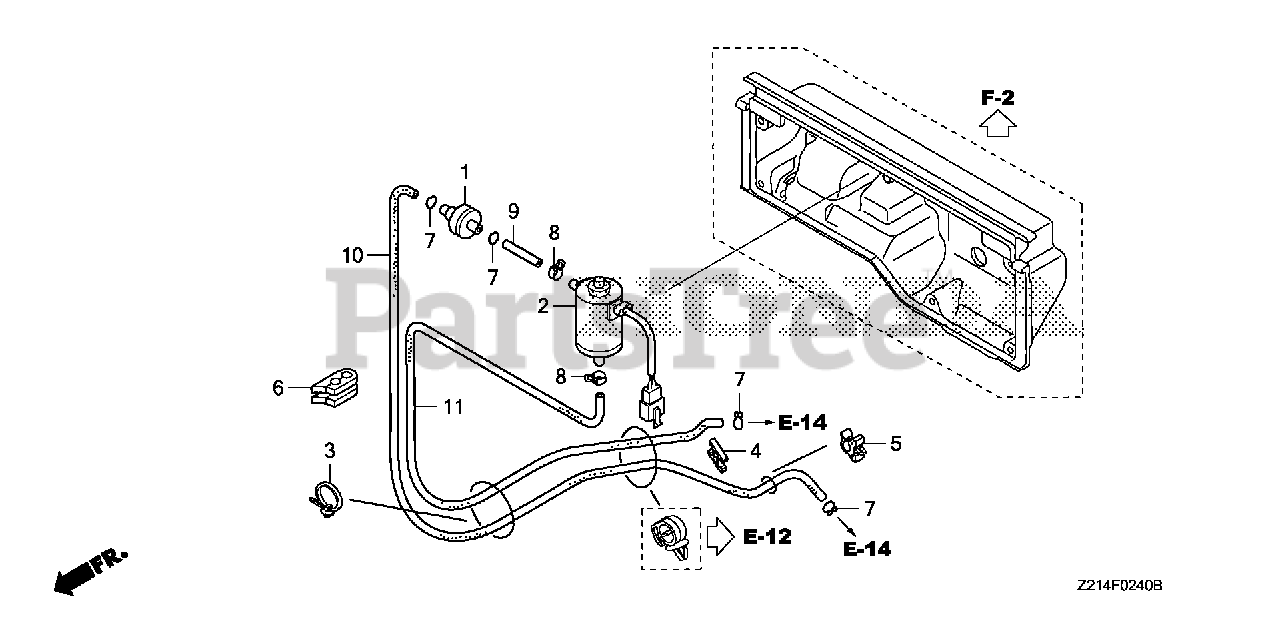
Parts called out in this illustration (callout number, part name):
1	VALVE, DASHPOT CHECK
2	VALVE ASSY., SOLENOID
3	BAND, HARNESS (98MM) (NATURAL)
4	CLIP, TUBE
6	GROMMET, TUBE
7	CLIP, TUBE (B7)
8	CLAMP, TUBE (D8)
9	BULK HOSE, VACUUM (3.5X8000) (3.5X30)
10	BULK HOSE, VACUUM (3.5X8000) (3.5X465)
11	BULK HOSE, VACUUM (3.5X8000) (3.5X650)
